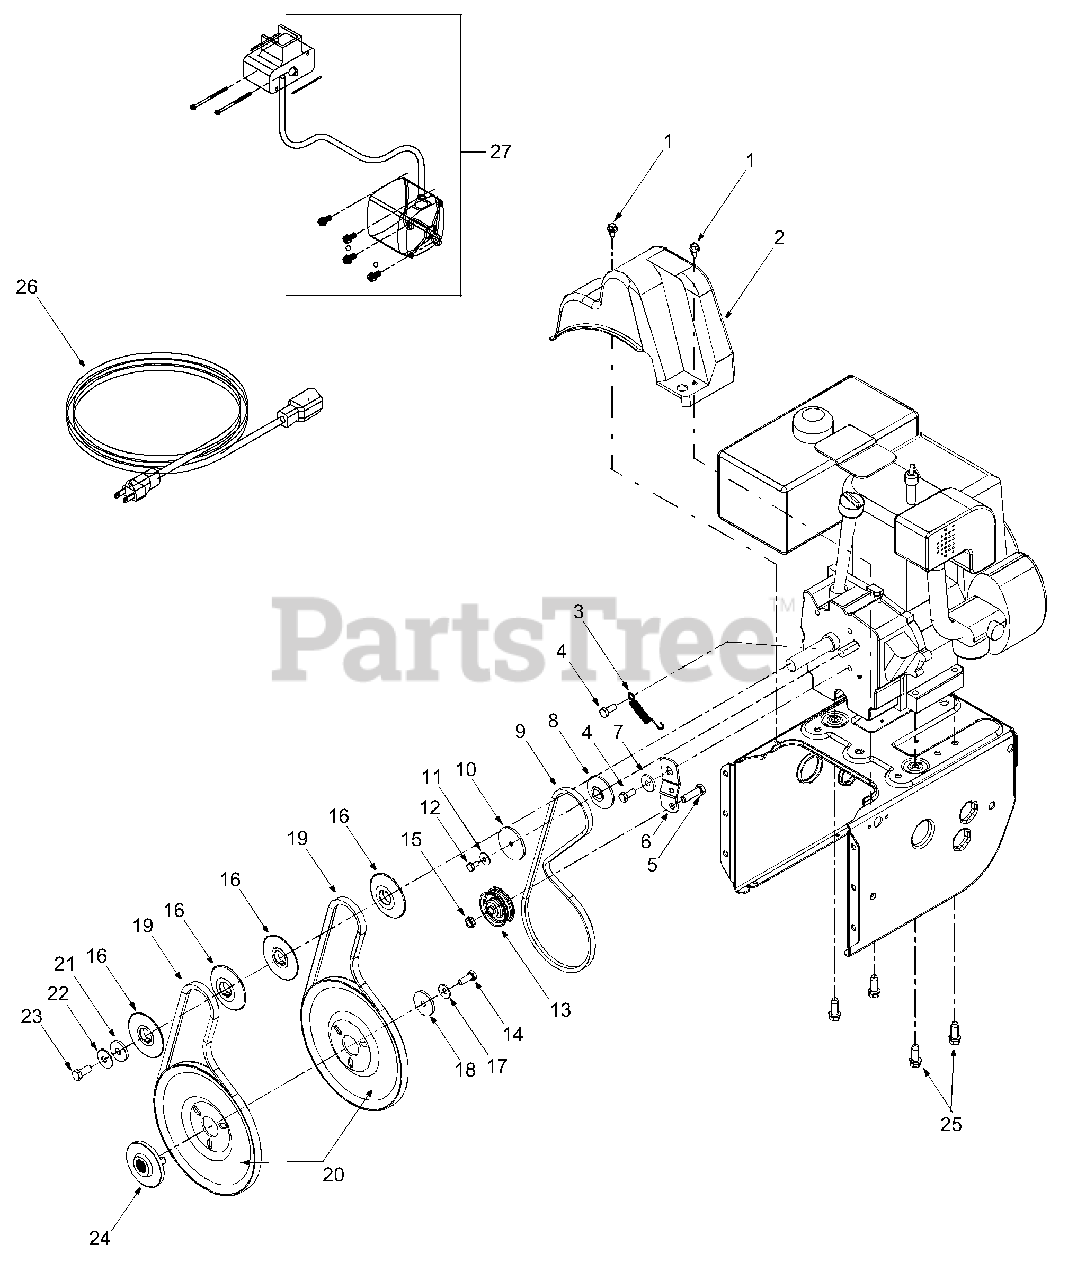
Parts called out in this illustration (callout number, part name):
1	Hex Washer Screw 1/4-20 x .625
2	Belt Cover
3	Extension Spring
4	Hex Screw 5/16-24 x .75
5	Hex Cap Screw 3/8-16 x 1.25
8	Pulley Half
9	V-Belt
10	Pulley Half
11	Bell Washer
12	Hex Cap Screw 1/4-28 x .50
13	Flat Idler
14	Lock Hex Cap Screw 5/16-24
15	Lock Jam Nut 3/8-16
16	Pulley Half
17	Bell Washer
18	Flat Washer
19	Belt
20	Auger Pulley
21	Flat Washer 3/8 x 1.25 OD
22	Bell Washer
23	Hex Cap Screw 3/8-24
24	Adapter Pulley
25	Hex Screw 3/8-16 x 1.0
26	Extension Cord
27	Electric Start Kit
